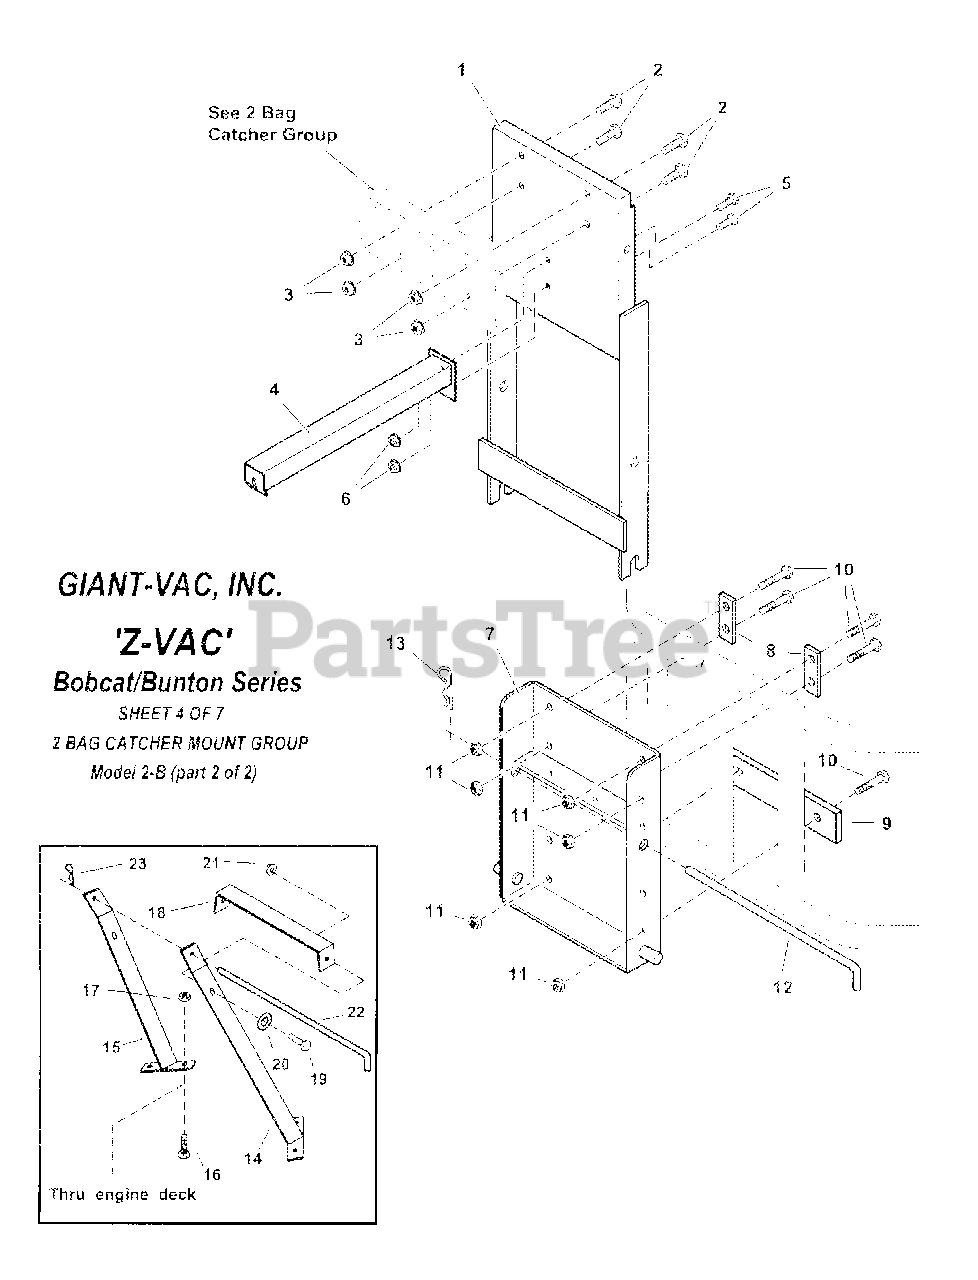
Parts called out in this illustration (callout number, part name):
1	WELDMENT, Bagger Mount Frame
2	SCREW, 3/8-16 x 3/4" Hex Head Cap, GR5
3	NUT, 3/8-16 Hex Flange Lock
4	ARM, Cover Latch
5	SCREW, 5/16-18 x 3/4" Hex Head Cap, GR5
6	NUT, 5/16-18 Hex Flange Lock
7	WELDMENT, Bumper Mounting Plate
8	BAR, Clamp
9	SHIM, Catcher Mount
10	SCREW, 3/8-16 x 1-1/4" Hex Head Cap
11	NUT, 3/8-16 Hex Flange Lock
12	ROD, Support
13	HAIRPIN, Clip
14	WELDMENT, Bagger Brace, RH Side
15	WELDMENT, Bagger Brace, LH Side
16	BOLT, 5/16-18 x 3/4" Short Neck Carriage, GR5
17	NUT, 5/16-18 Hex Flange Lock
18	CATCHER BRACE, Center, 2 Bag Bobcat
19	SCREW, 3/8-16 x 1-1/4" Hex Head Cap
20	WASHER, 3/8" Flat
21	NUT, 3/8-16 Hex Flange Lock
22	ROD, Bagger Brace Locking
23	HAIRPIN, Cotter
